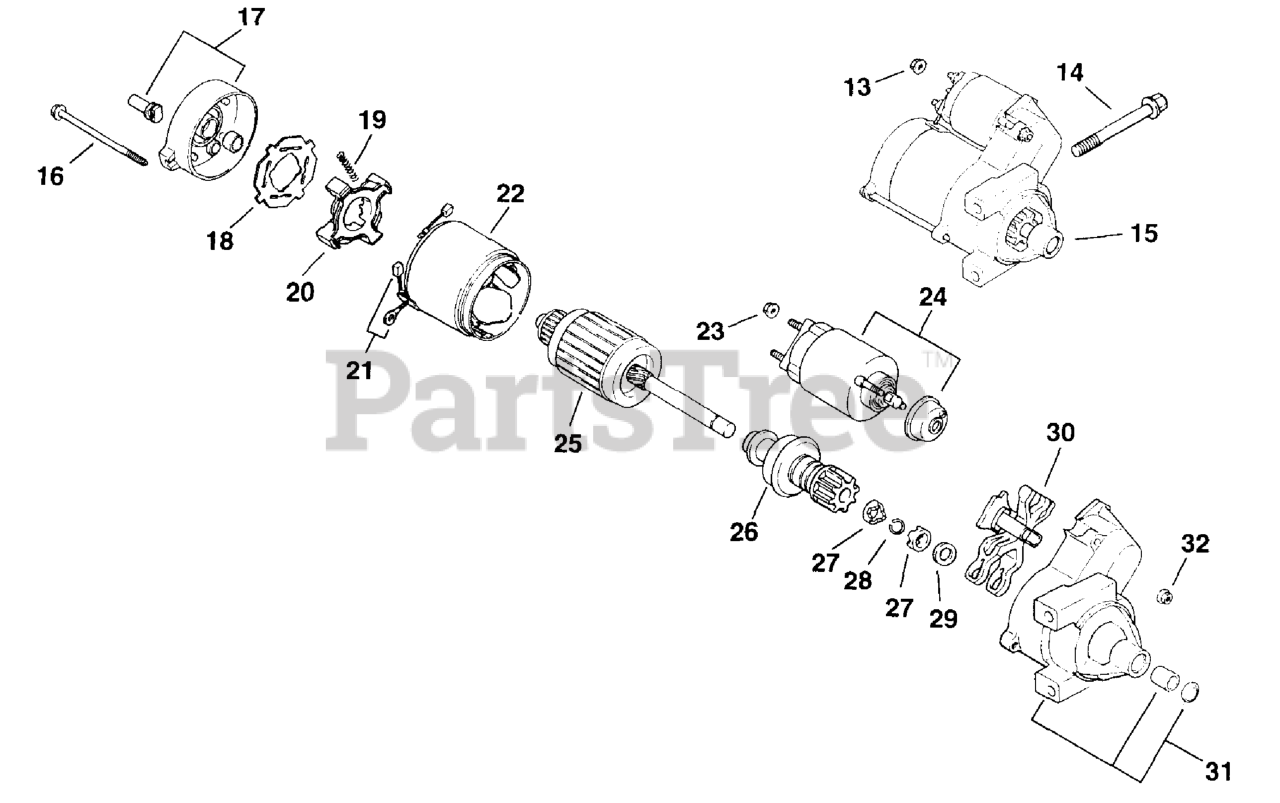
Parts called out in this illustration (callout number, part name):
13	NUT - USE M-841080
14	Screw, hex. flange M8x1.25x80.6
16	THRU BOLT
17	COMMUTATOR END CAP - DISCONTINUED
18	INSULATOR
19	SPRING, BRUSH
20	BRUSH HOLDER
21	BRUSH & SPRING KIT
22	FRAME W/BRUSHES - DISCONTINUED
25	ARMATURE - DISCONTINUED
26	DRIVE PINION
27	KIT - USE 24 755 84
28	KIT - USE 24 755 84
29	KIT - USE 24 755 84
30	LEVER, DRIVE
31	DRIVE END CAP
